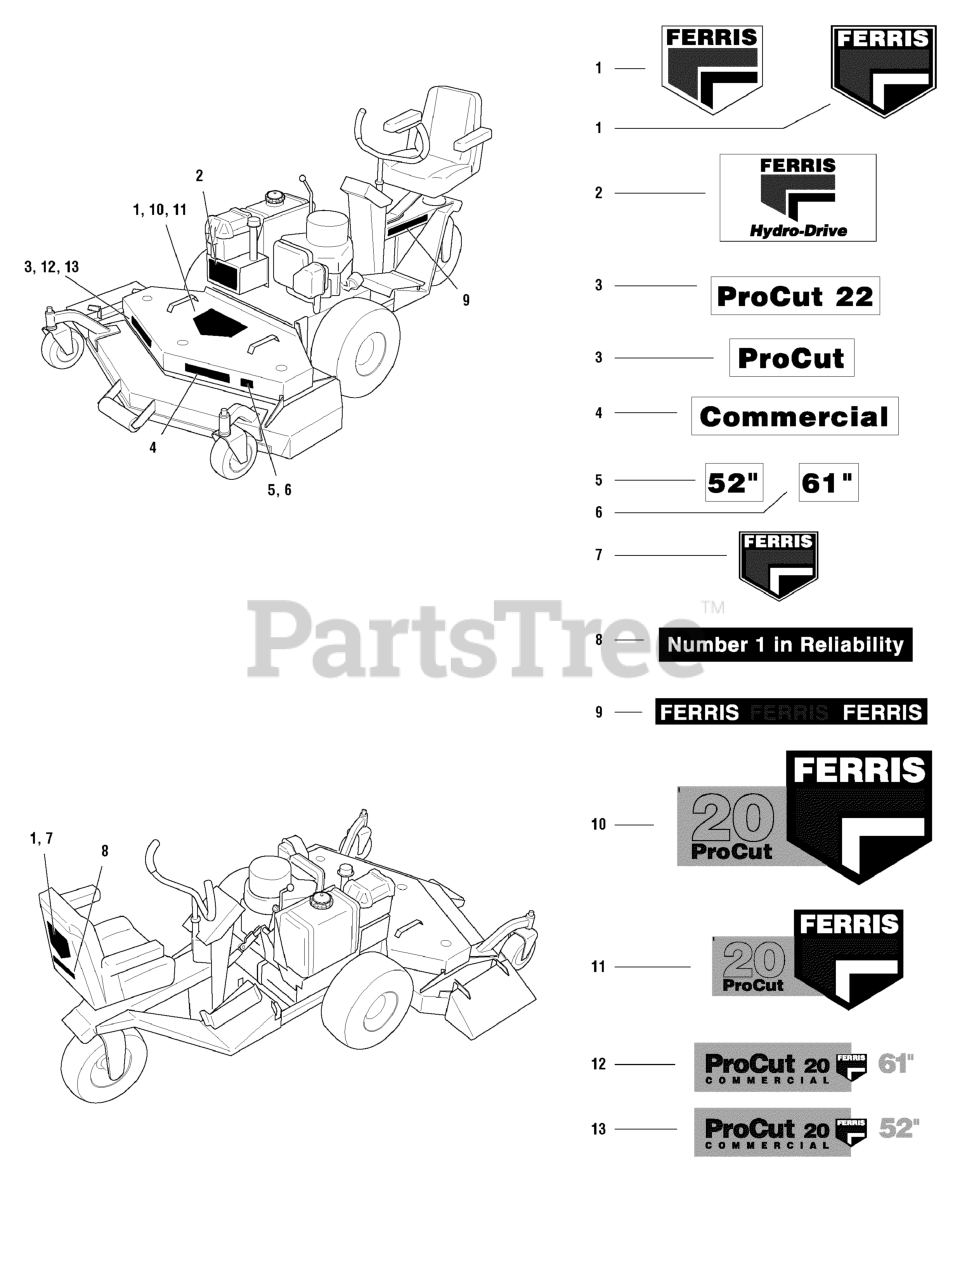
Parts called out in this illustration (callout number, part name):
1	DECAL, Ferris Logo, 10-3/4"
2	DECAL, Hydro Drive
3	DECAL, ProCut 22
3	DECAL, ProCut
4	DECAL, Commercial
5	DECAL, 52
6	DECAL, 61"
7	DECAL, Ferris Logo, 6-3/8"
8	DECAL, Number One In Reliability
9	DECAL, Ferris Text
10	DECAL, Ferris Logo (61" deck)
11	DECAL, Ferris Logo (52" deck)
12	DECAL, ProCut 2061
13	DECAL ProCut 2052
